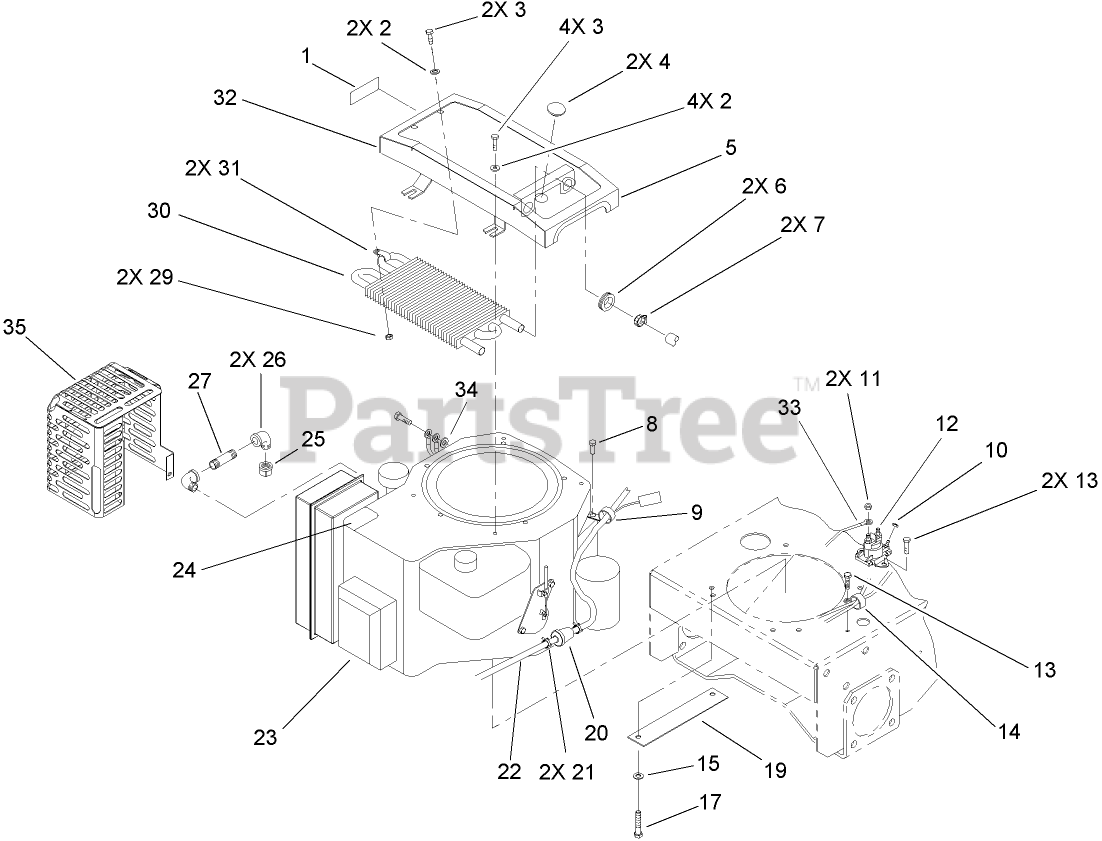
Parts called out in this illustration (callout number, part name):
1	DECAL-SHUT OFF, FUEL
2	WASHER-FLAT
3	SCREW-HH
4	PLUG-PLASTIC
5	TRIM-MOUNT, COOLER
6	GROMMET
7	CLAMP-HOSE
8	SCREW-SHWH
9	CLAMP-R
10	NUT-KEPS
11	NUT-KEPS
12	SOLENOID
13	SCREW-HWH
14	CLAMP-R
15	WASHER-PLAIN
17	SCREW-HH
19	COVER-PULLEY
20	FILTER-FUEL
21	CLAMP-HOSE
22	HOSE-FUEL
24	DECAL-SURFACE, HOT
25	CAP-PIPE
26	ELBOW-STREET, 90 DEG
27	NIPPLE-PIPE
29	NUT-LOCK, NI
30	COOLER-OIL
31	CLAMP-R
32	MOUNT-COOLER
33	WIRE ASM
34	WASHER-LOCK
35	Guard-Muffler
